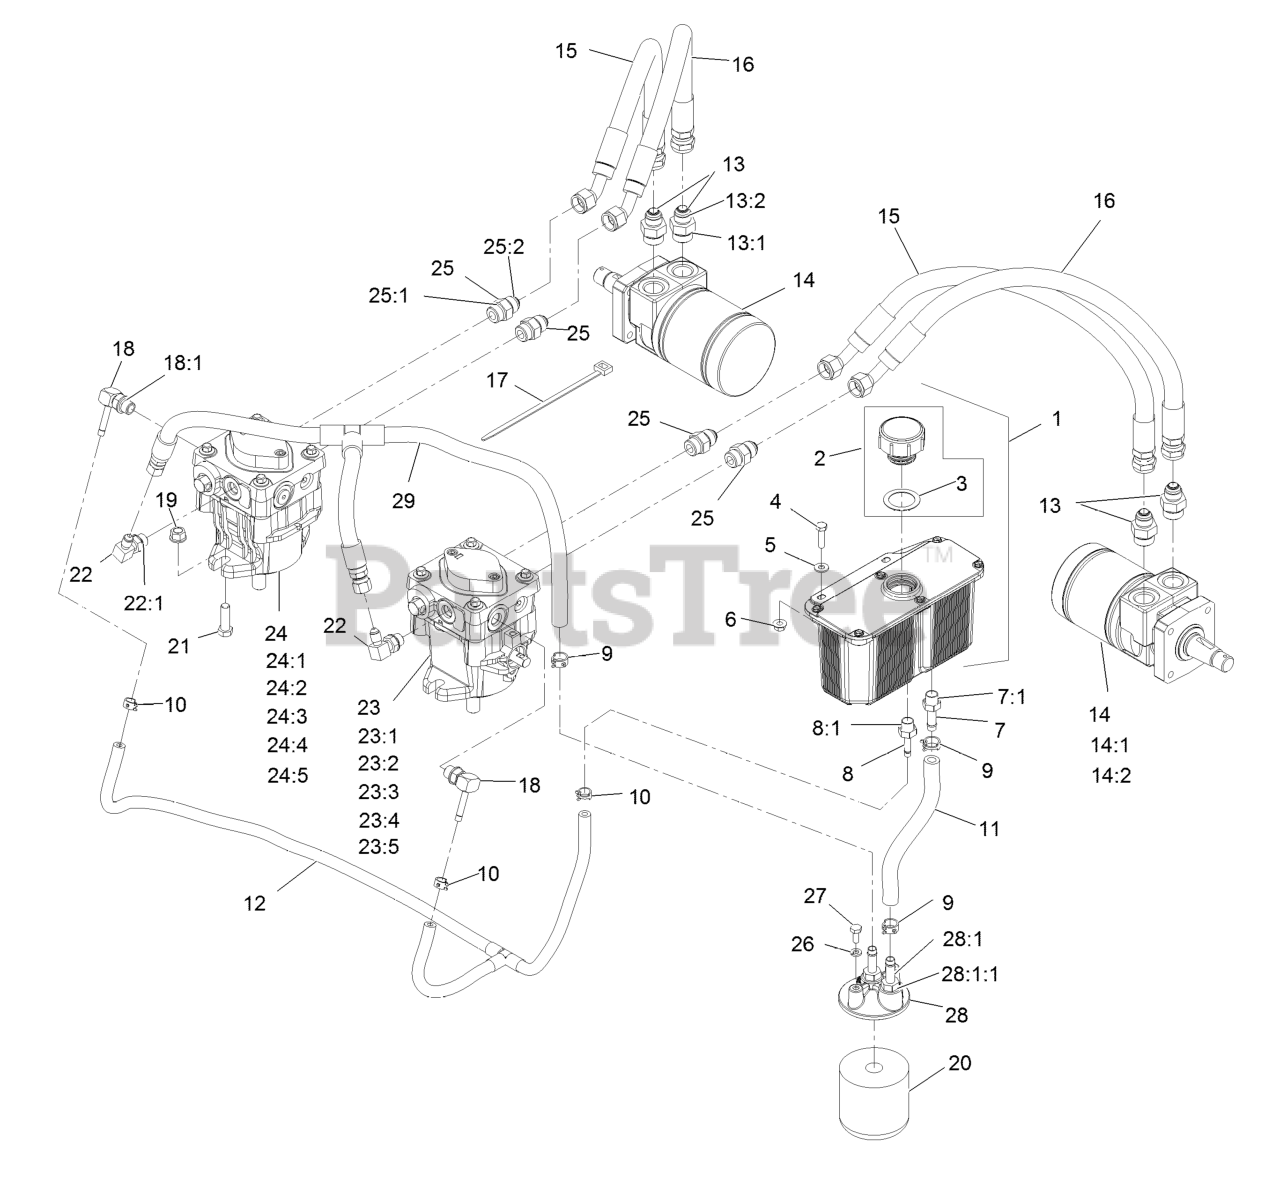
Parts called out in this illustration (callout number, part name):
1	HYD RESERVOIR ASM
2	KIT,HYD RES CAP W/GASKET
3	GASKET-CAP
4	SCREW-HH
5	WASHER-FLAT
7	ADAPTER-STRAIGHT
8	ADAPTER-STRAIGHT
9	CLAMP-HOSE
10	CLAMP-HOSE
11	HOSE,CASE DRAIN RH
12	ASM,CASE DRAIN HOSE
13	FITTING-STRAIGHT
14	HYD MOTOR ASM
14:1	SEAL KIT
14:2	BEARING AND SEAL KIT
15	HOSE,HYDRAULIC W/COVER
16	HOSE,HYDRAULIC W/COVER
17	TIE-PLASTIC
18	ELBOW-90 DEG
19	NUT-FLANGE
20	FILTER-25 MICRON, BI-DIRE
20	ELEMENT-FILTER, WINTER
21	SCREW-HH
22	FITTING-ELBOW, 90 DEG
23	PUMP-HYD PE RH TTH
23:1	INPUT SHAFT KIT
23:2	BEARING-THRUST
23:3	CYLINDER BLOCK KIT
23:4	SEAL OVERHAUL KIT
23:5	KIT, 10CC PUMP KIT
24	PUMP-HYD PE LH TTH
24:1	INPUT SHAFT KIT
24:2	BEARING-THRUST
24:3	CYLINDER BLOCK KIT
24:4	SEAL OVERHAUL KIT
24:5	KIT, 10CC PUMP KIT
25	FITTING-STRAIGHT
26	WASHER-LOCK
27	SCREW-HH
28	FILTER HEAD ASM
28:1	ADAPTER-STRAIGHT
29	ASM,CHARGE HOSE
